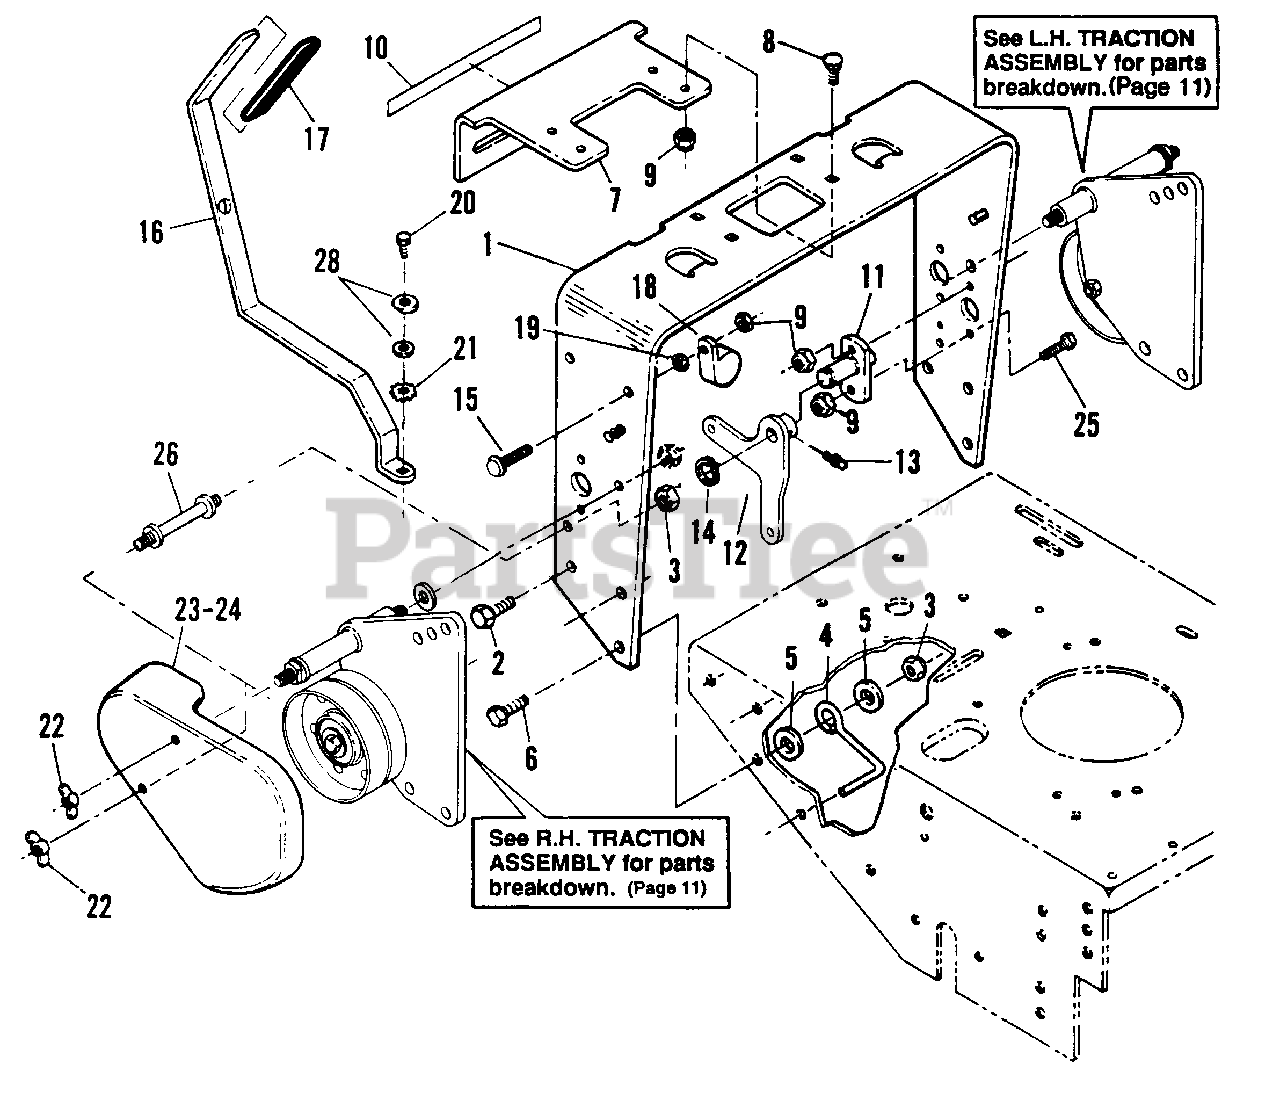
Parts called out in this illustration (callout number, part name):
1	TANK BRACKET
2	SCREW, 3/8" C x 1" Lg. Hex Cap
3	NUT, 3/8" C Nyloc
4	GUIDE, Traction Belt
5	WASHER, 3/8" Flat
6	SCREW, 3/8" C x 1 1/4" Lg. Hex Cap
7	QUADRANT, Shift
8	BOLT, 1/4" C x 3/4" Lg. Carriage
9	NUT, 1/4" C Nyloc
10	DECAL, Shift
11	MOUNT, Bellcrank
12	WELDMENT, Blade Bellcrank
13	GREASE FITTING, 1/4" - 28 Str. Zerk
14	RING, 5/8" External Retaining
15	BOLT, 1/4 - 20 x 3/4" Carriage
16	LEVER, Shifter
17	GRIP, Shift Lever
18	MODULE (Kawasaki)
19	LOCKWASHER, 1/4" Int. Tooth
20	SCREW, 1/4" - 28 x 5/8" Lg. Hex Cap
21	LOCKWASHER, 1/4" Int/Ext. Tooth
22	WINGNUT, 3/8" C Nyl. Ring
23	FENDER, R.H.
25	SCREW, 1/4" x 3/4" Lg. Hex. Cap
26	STUD, Fender Mount
28	WASHER, 1/4" Flat SAE
